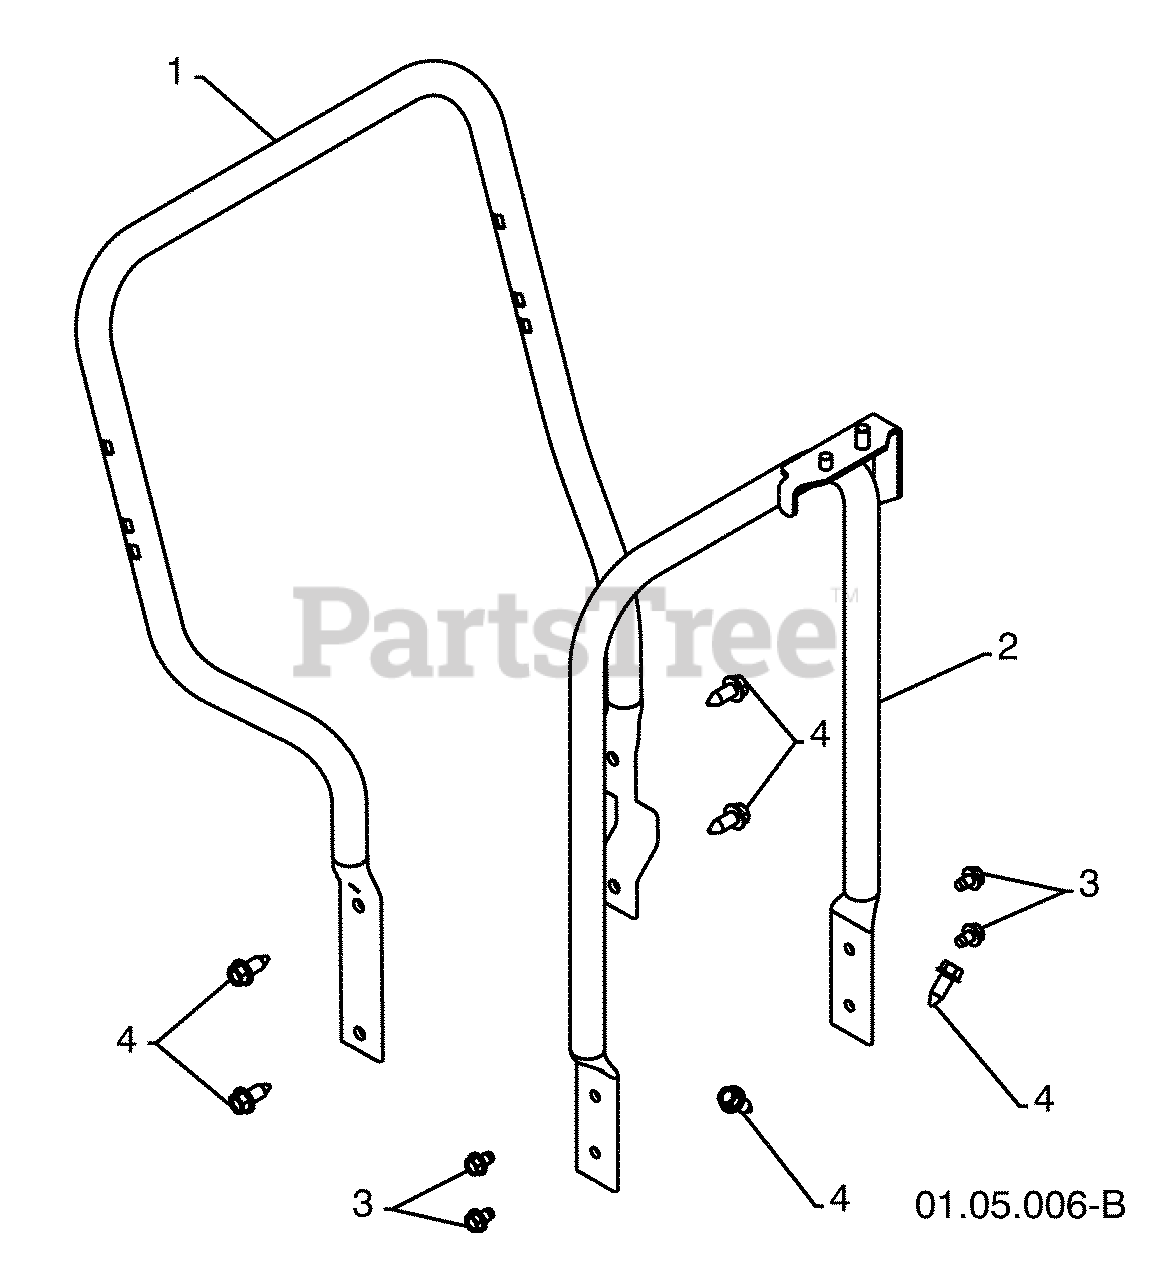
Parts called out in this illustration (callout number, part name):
1	LOWER TUBE GRAY
2	PIVOT SUPPORT
3	BOLT 5/16-18 X .750
4	SCREW 3/8-16 X 1.00
